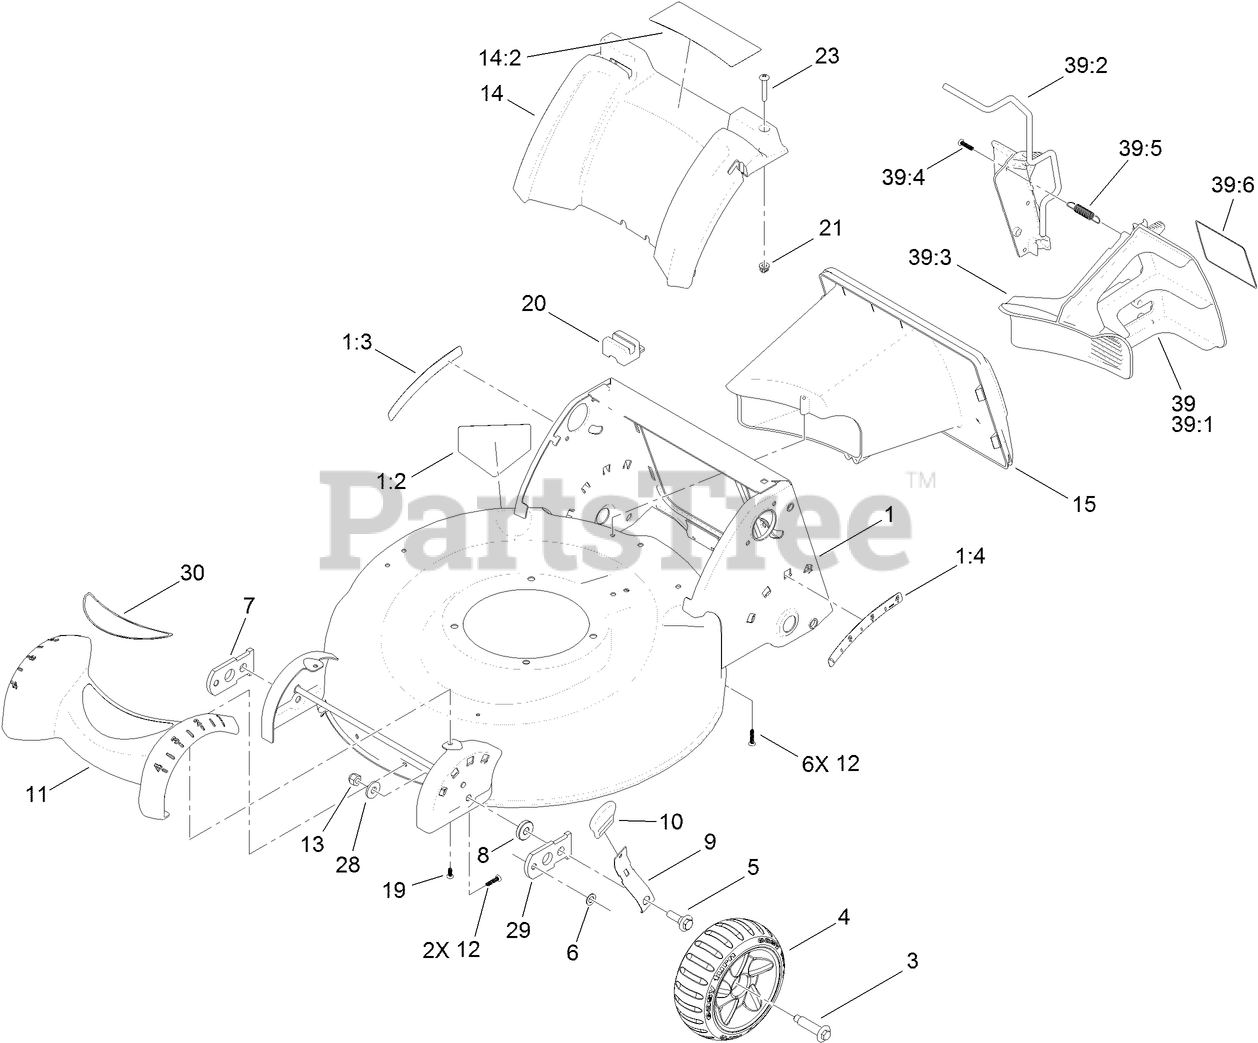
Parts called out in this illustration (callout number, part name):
1	21 INCH DECK ASM
1:2	DECAL-DANGER
1:3	DECAL-HOC, RH
1:4	DECAL-HOC, LH
3	BOLT-SHOULDER
4	7 INCH WHEEL AND TIRE ASM
5	SCREW-SHOULDER, HWH
6	WASHER
7	ARM-PIVOT, RH
8	WASHER
9	ARM-SPRING
10	KNOB-HOC
11	COVER-FRONT
12	SCREW-PLASTITE
13	NUT-LOCK, NI
14	REAR COVER ASM
14:2	DECAL-WARNING
15	TUNNEL
19	SCREW-PLASTITE
20	MODULE-SWITCH
21	NUT-CLIP
23	SCREW-PTH
28	WASHER-HARDENED
29	ARM-PIVOT, LH
30	DECAL-FRONT (CE)
39:1	PLUG-MULCH, LH
39:2	LATCH-PLUG, MULCH
39:3	PLUG-MULCH, RH
39:4	SCREW-PLASTITE
39:5	SPRING-EXTENSION
39:6	DECAL-PLUG, MULCH
